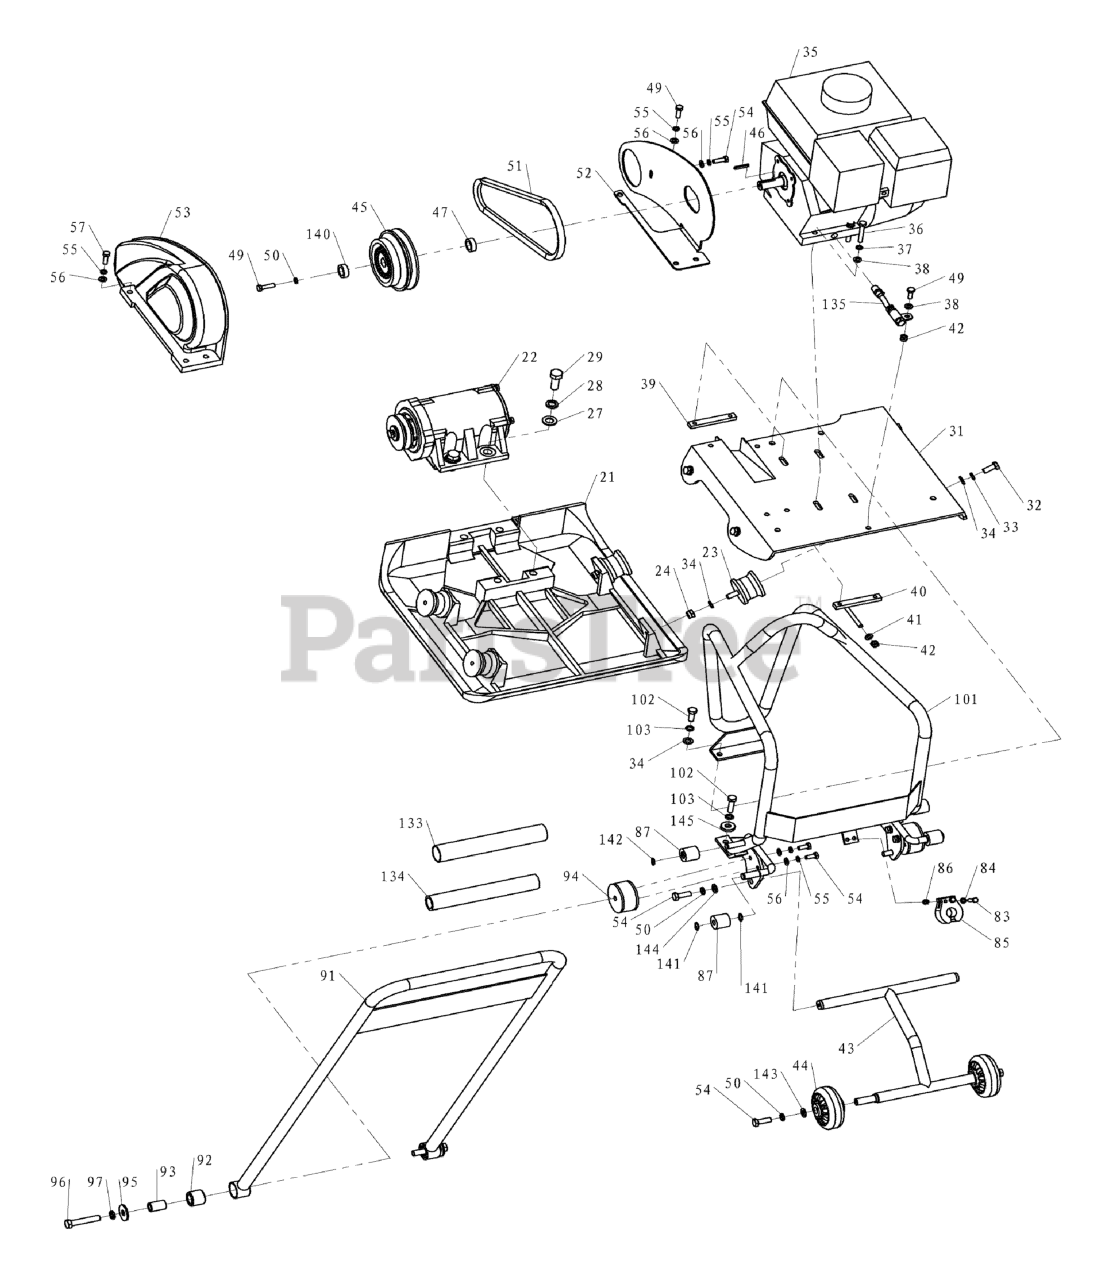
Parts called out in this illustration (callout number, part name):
21	BASE PLATE
22	VIBRATION BOX
23	VIBRATION RUBBER
24	NUT, Nylon, M10, GB170
27	WASHER, 16
28	WASHER, Spring, 16
31	ENGINE BASE
32	BOLT, M10 × 25, GB5783
33	WASHER, Spring, 10, GB93
34	WASHER, 10, GB95
35	ENGINE, Briggs & Stratton
36	BOLT, M8 x 40, GB5738
37	WASHER, Spring, 8, GB93
38	WASHER, 8, GB95
39	CLAMP, Engine Nut
40	CLAMP, Engine Nut
41	WASHER 8
42	NUT, Nylon
43	FRAME, Road Wheel
44	ROAD WHEEL
45	CLUTCH ASSEMBLY
46	KEY, 5 x 32
47	BUSHING
49	BOLT, M8 x 30, GB5738
50	WASHER, Spring, 8, GB93
51	V-BELT, XPA882
52	INSIDE BELT COVER
53	BELT COVER
54	BOLT, M8 x 20, GB5783
55	WASHER, Spring, 8, GB93
56	WASHER, 8, GB95
57	BOLT, M8 x 20, GB5783
83	BOLT, M6 x 35
84	WASHER, 6
85	CLIP, Rubber
86	NUT, M6
87	COLLAR, Rubber
91	HANDLE
92	COLLAR
93	RUBBER
94	RUBBER MOUNT
95	WASHER
96	BOLT, M12 x 50, GB5780
97	SPRING WASHER 12 - GB93
101	GUARD HOOK
102	BOLT, M10 × 35, GB5783
103	WASHER, Spring, 10, GB93
133	FOAM, Handle
134	SHEATH, Handle
135	DRAIN PIPE ASSEMBLY
140	KEY, Bushing
141	RING SHIELD,14
142	RING SHIELD,12
143	WASHER
144	BUSHING
145	WASHER, Large, 28.5 x 11 x 6
